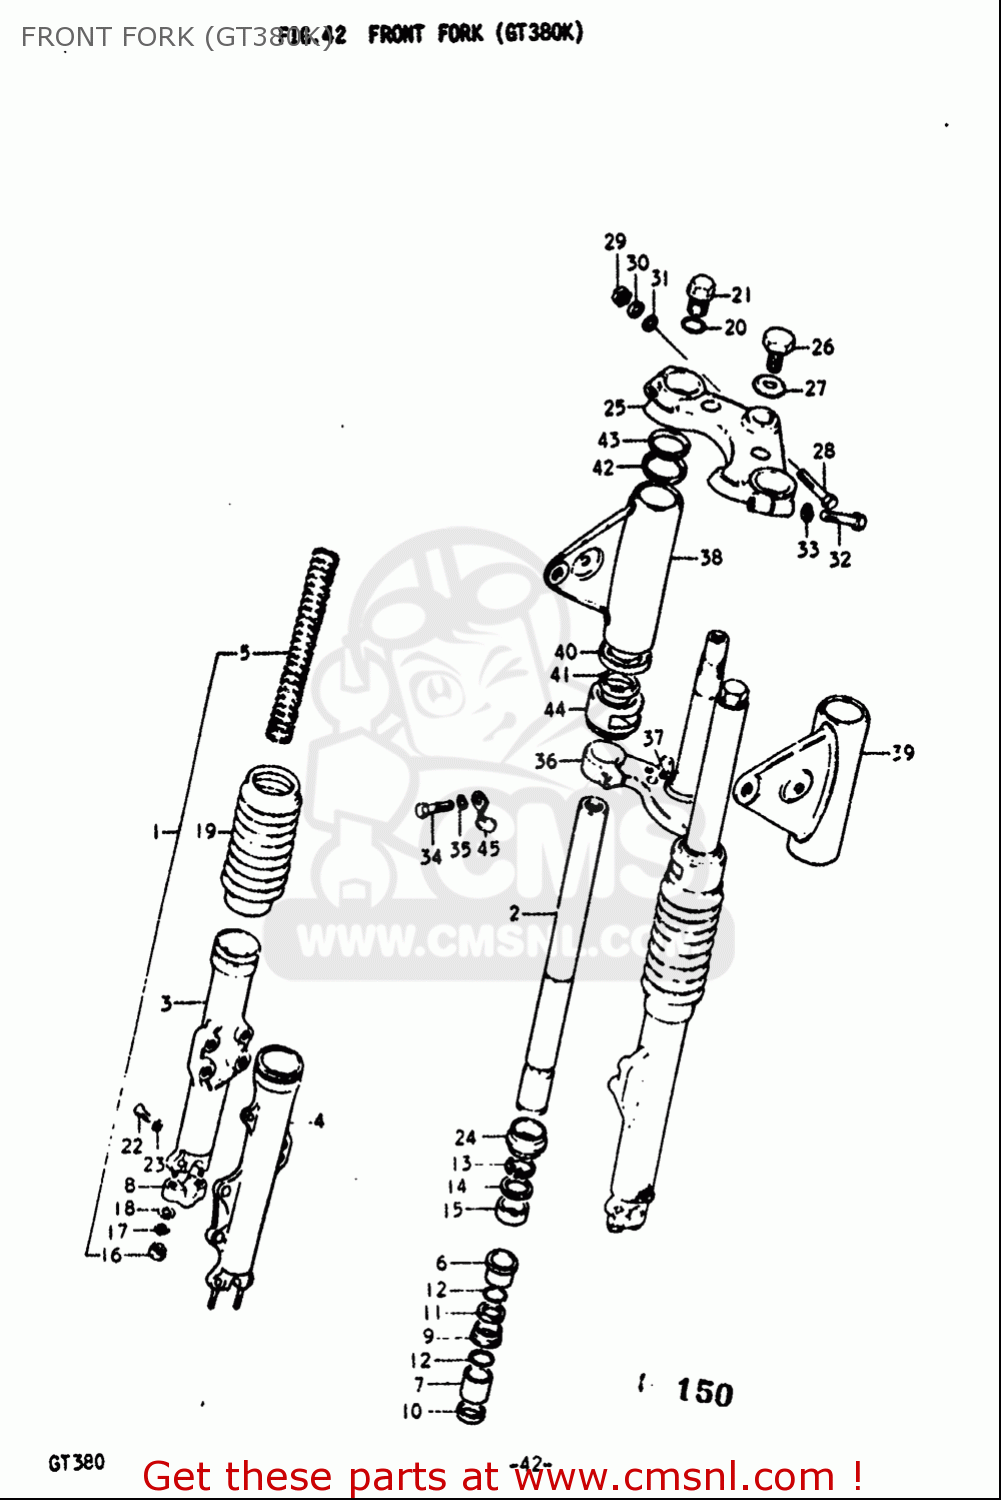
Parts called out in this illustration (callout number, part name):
8	HOLDER,AXLE
15	SEAL,OIL
16	NUT
17	WASHER,LOCK
18	WASHER
19	BOOT
22	SCREW 4X6
23	GASKET (NAS)
29	NUT
30	WASHER,LOCK
31	WASHER
32	BOLT
33	WASHER,LOCK
34	BOLT
35	WASHER,LOCK
37	RACE,STEERING OUTER LWR
40	GUIDE
41	CUSHION,HEADLAMP BRACKET
42	GUIDE
43	CUSHION,HEADLAMP BRACKET UPR
45	CLIP,SPEEDOMETER CABLE
